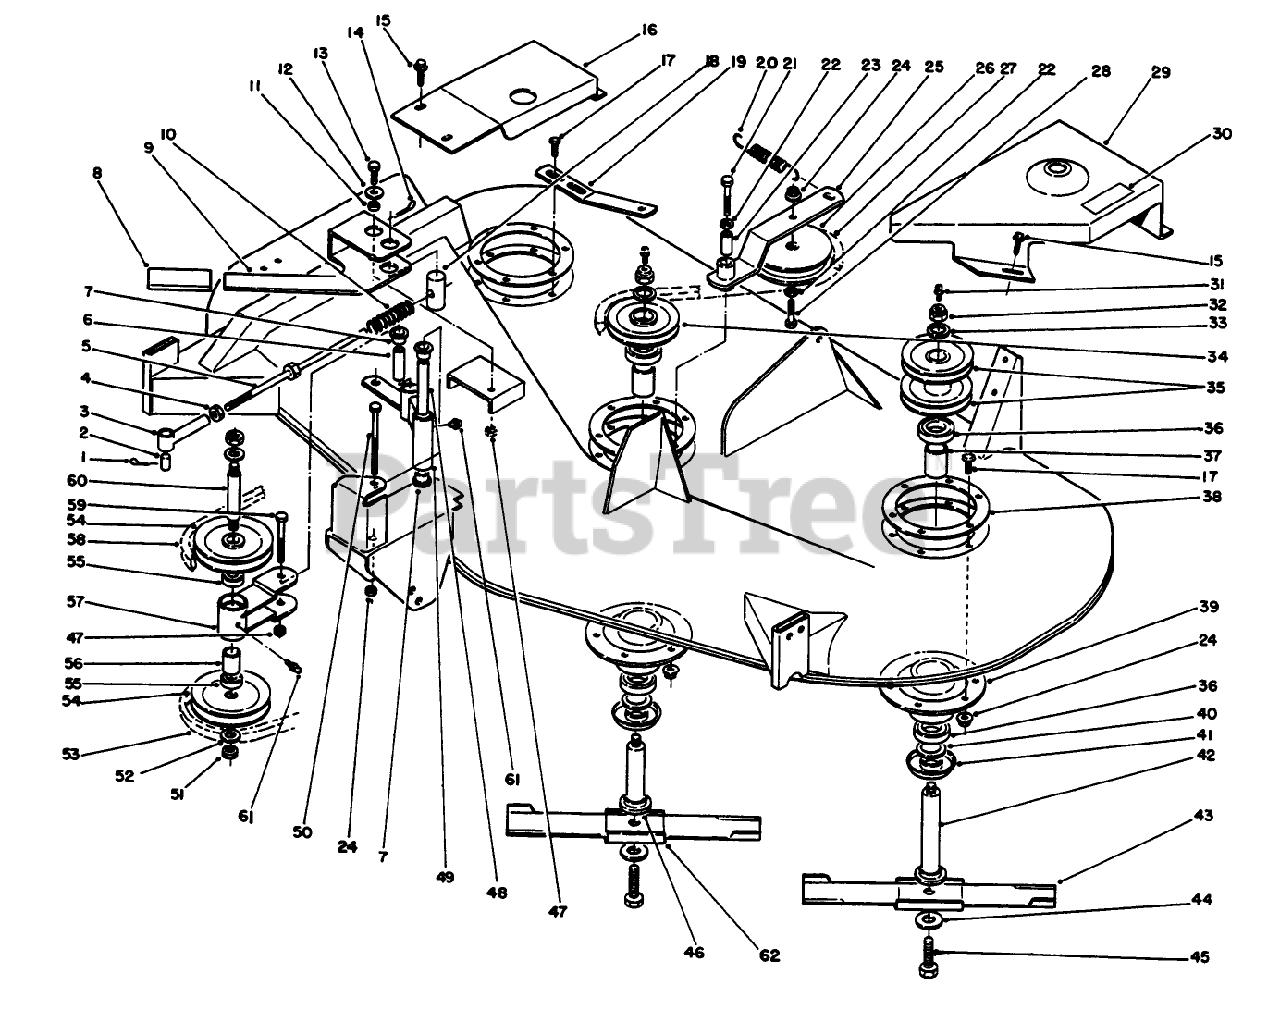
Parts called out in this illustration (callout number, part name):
1	PIN-COTTER
2	PIN-CLEVIS
4	NUT-JAM
5	ROD-W.A. R
6	SPACER
7	BUSHING
9	Lever
10	SPRING-COMPRESSION
11	SPACER
12	WASHER-FLAT
13	SCREW-HH
14	PIN-COTTER
15	SCREW-HHFTF
16	Cover-Belt, R.H.
17	SCREW-CARR
18	TRUNNION
19	Strap-Spring
20	SPRING-EXTENSION
21	SCREW-HH
22	WASHER-FLAT
23	SLEEVE
24	NUT-HF
25	Arm-Idler
26	PULLEY-IDLER
27	V-BELT
28	SCREW-HH
29	Cover-Belt L.H.
30	DECAL-HOC
31	FITTING-GREASE
32	NUT-JAM
33	WASHER-FLAT
34	PULLEY
35	PULLEY-L.H. R
36	BEARING-BALL
37	SPACER-BEARING
38	SUPPORT-DECK, RING
39	Housing-Spindle
40	WASHER-WHEEL
41	SHIELD-BEARING
42	SHAFT-SPINDLE
43	Blade
44	WASHER-FLAT
45	SCREW-BLADE
46	SHAFT-SPINDLE
47	NUT-LOCK, NI
48	SPACER
49	Arm Assembly
50	SCREW-HH
51	NUT-JAM
52	WASHER-LOCK
53	V-BELT
54	PULLEY R
55	BEARING-BALL
56	SPACER
57	Arm Assembly
58	V-BELT
59	SCREW-HH
60	COUNTER-SHAFT
61	FITTING-GREASE
62	STIFFENER-BLADE
